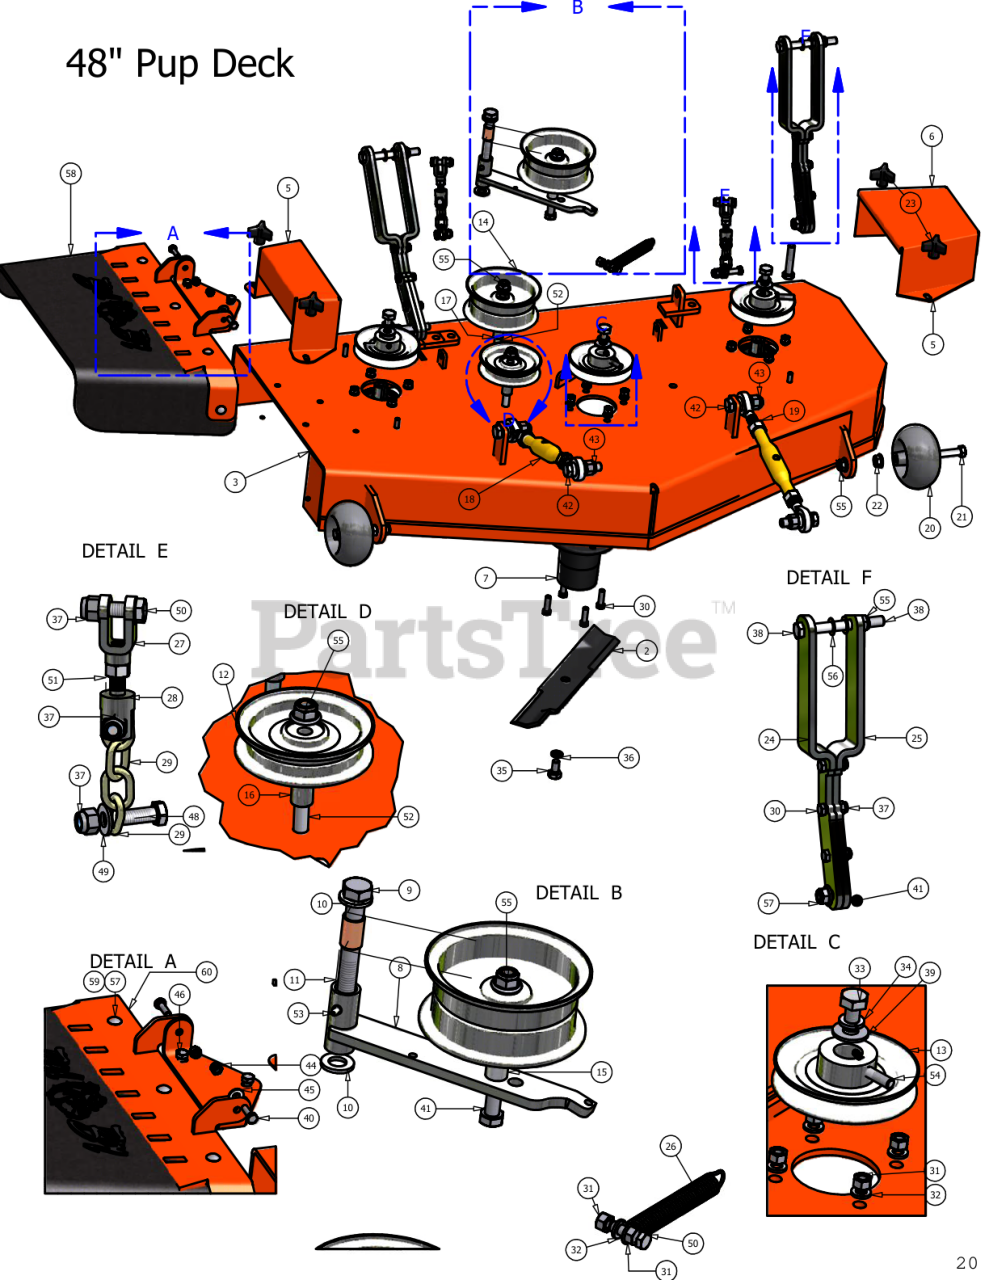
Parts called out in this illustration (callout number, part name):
1	48" Deck Belt
2	48" Fusion Blade
4	Descharge Chute Hanger
5	48" Spindle Cover
6	Spindle Cover
8	Deck Ider Arm
9	5/8" x 4" Hex Bolt
10	.635 ID Plastic Washer
11	5/8" ID x 1 1/8" Brass Bushing
12	4 3/4" Idler Pulley
13	5" Dsck Pulley
14	5 3/4" Deck Idler Pulley
15	1 1/4" Pulley Spacer
16	Turnbuckle
17	3/4" Left Handed Nut
18	Anti-Scalp Roller
19	1/2" x 4" Bolt
20	1/2" Flange Nut
21	5/16" Knob
22	Deck Support Arm (Left)
23	Deck Support Arm (Right)
24	Deck Idler Spring
25	Female Yoke
28	3/8" x 1 1/4" Hex Bolt
29	3/8" Hex Nut
30	3/8" Lock Washer
31	1/2" x 1 1/2" Hex Bolt
32	1/2" Lock Washer
33	5/8" x 1 1/2" Bolt
34	5/8" Lock Washer
35	3/8" Nylock Nut
36	1/2" x 4 1/2" Bolt
37	1/2" Cuppded Washer
38	5/16" x 1" Hex Bolt
39	1/2" x 2 1/2" Hex Bolt
40	5/8" Nylock Nut
41	3/8" Std NC Nylock Nut
42	.360 ID Plastic Washer
43	3/8" x 3/4" Hex Bolt
44	3/8" Flat Washer
45	3/8" x 1 1/2" Hex Bolt
46	3/8" Fine threaded Jam Nut
47	1/2" x 3 1/2" Bolt
48	Grease Fitting
49	3/8" Hex Bolt
50	1/2" Flange Lock Nut
51	1/2" Brass Washer
52	5/16" x 1 1/2" Carriage Bolt
53	Rubber Side Discharge
54	5/16" Nylock Flange Nut
55	2007 Hanger Plate
56	2007 Lower Hanger Plate
